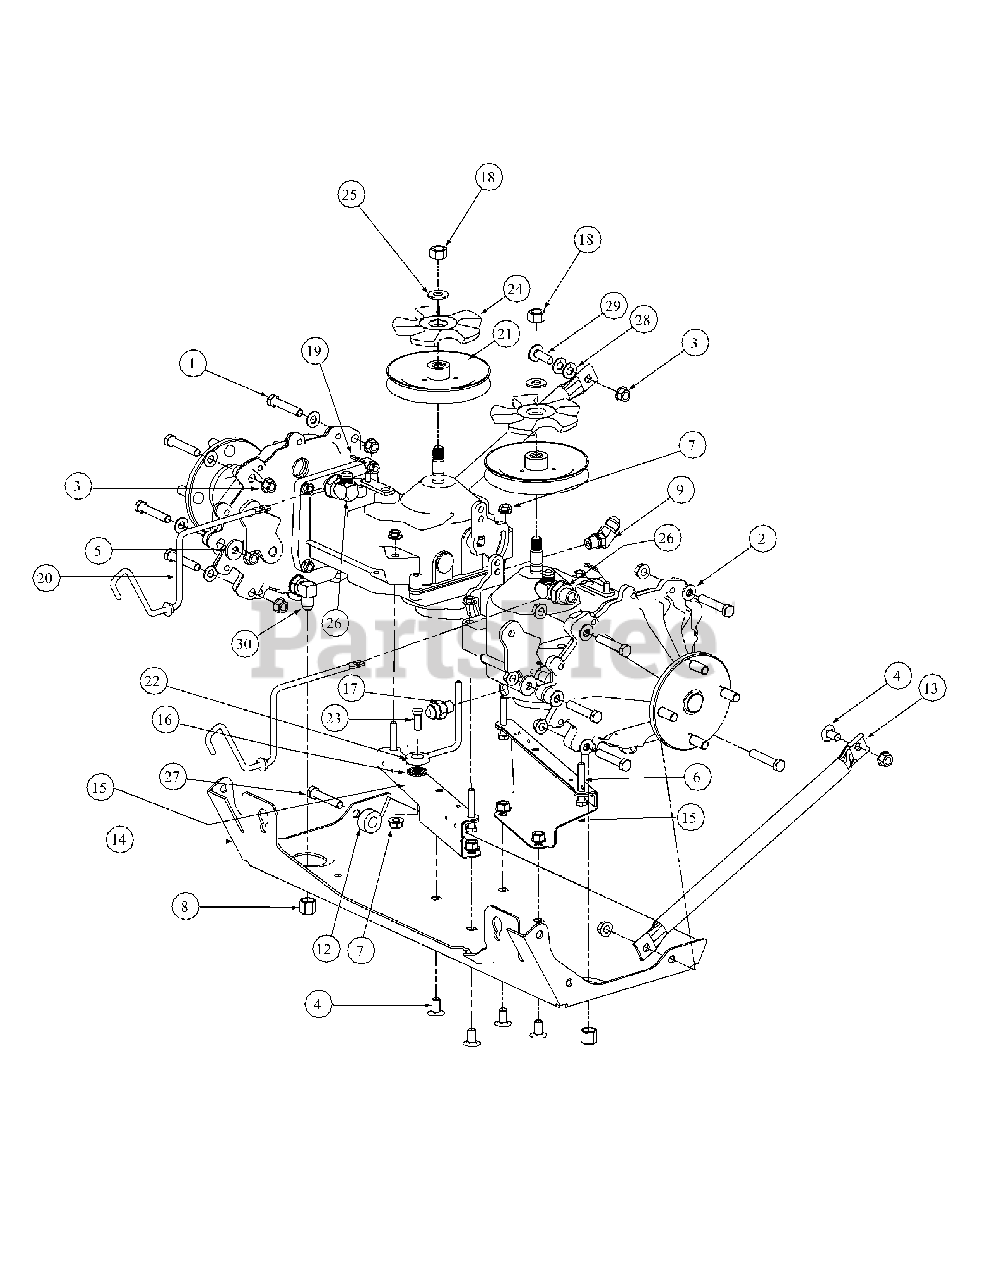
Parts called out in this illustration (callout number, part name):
1	HHCS, 3/8-16, 2.00
2	Flat Washer, 3/8, SAE
3	Hex Nut, 3/8-16, Flange Lock
4	Carriage Bolt, 3/8-16 x .75 Long
5	Flat Washer, .385 x 1.0 OD x .13
6	HHCS, 5/16-18, 2.00
7	Lock Nut, Hex Flange, 5/16-18
8	Nut, Cap, 3/8
9	Elbow Fitting, 3/8-1/2, 45 degree
12	Spacer, .406 ID x 1.00 OD x .38
13	Strut, Frame
14	Plate Assembly, Skid
15	Bracket Assembly, Support Pump
16	External Tooth Washer
17	Fitting Connector, 1/2 x 3/8
18	Nut, 1/2-20, Hex Insert Lock Jam
19	Hair Pin, .0721 x 1.12 Long
20	Rod, Release, Pump
21	Pulley, Transmission Hydro, Slotted
22	Guide, Traction Drive Belt
23	Flat Head Screw, 5/16-18 x 1.00
24	Hydro Pulley Fan
25	1/2" Flat Washer
26	Fitting Elbow, 3/8 x 3/8
27	Hex Cap Screw, 3/8-16, 2.50
28	Lock Washer, 3/8
29	Carriage Bolt, 3/8-16 x 1
30	Fitting Elbow, 3/8 x 3/8
